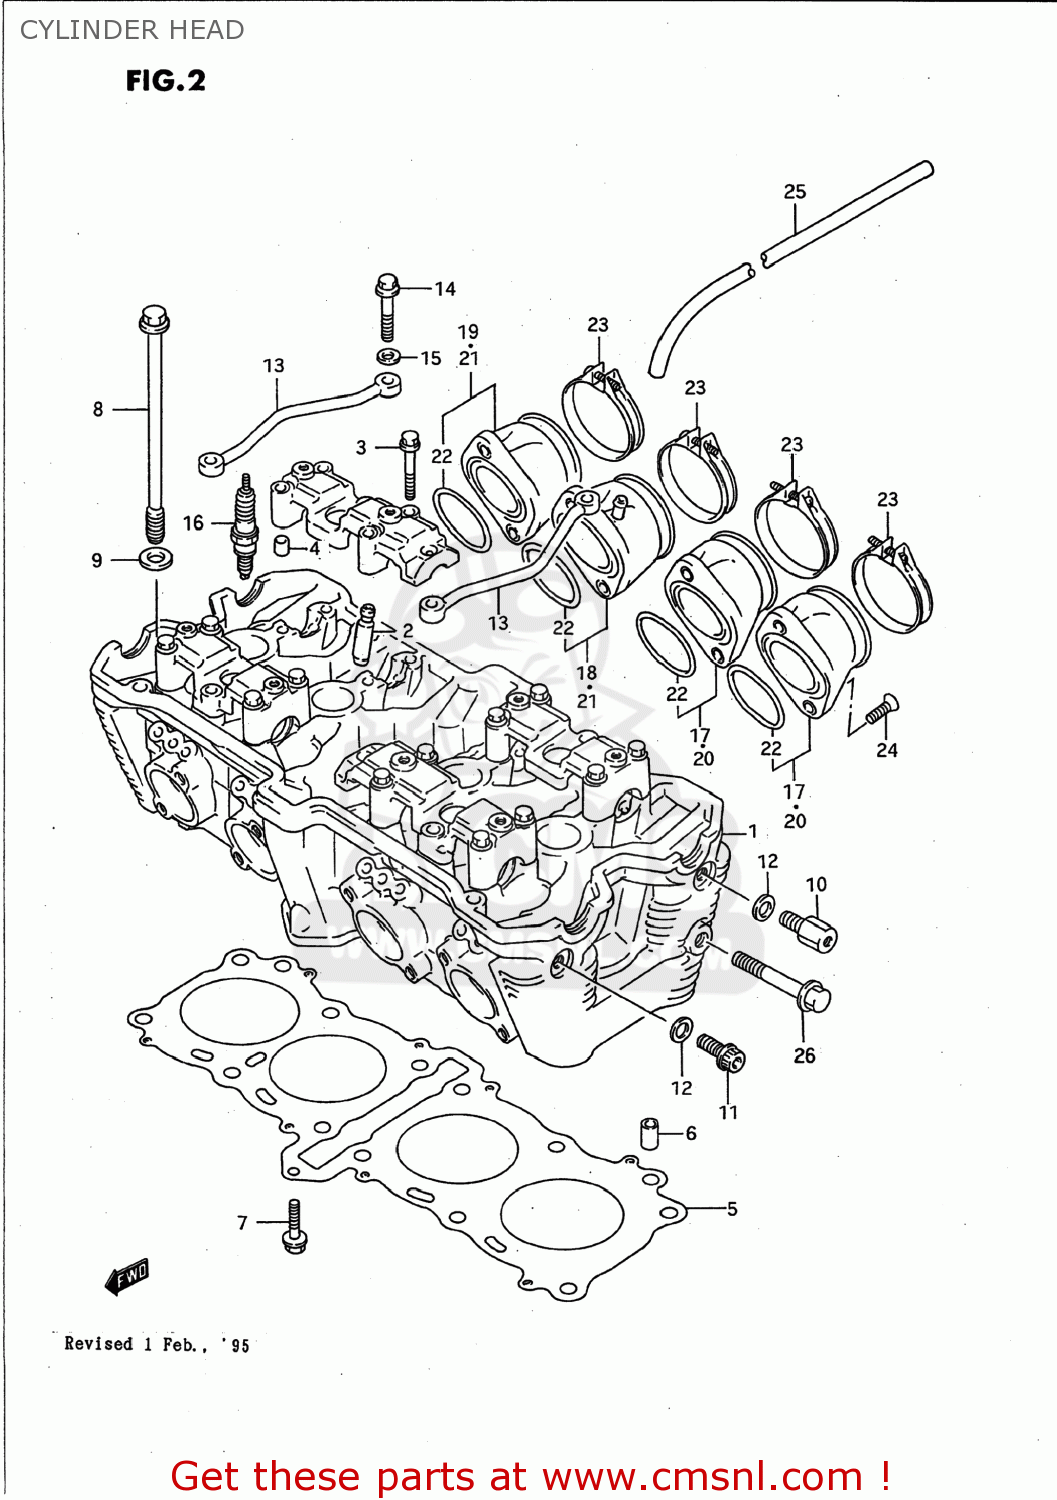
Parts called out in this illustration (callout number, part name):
1	HEAD ASSEMBLY,CYLINDER
2	GUIDE,VALVE
3	BOLT
4	PIN(6.2X8X11)
5	GASKET,CYLINDER HEAD
6	PIN
7	BOLT
8	BOLT(10X160)
9	WASHER(10.5X19X2)
10	BOLT
11	BOLT
12	GASKET(8.2X14X1).6 (NAS)
13	PIPE,CYLINDER HEAD OIL
14	BOLT(6X39)
15	WASHER
16	PLUG,SPARK(CR8E)
17	PIPE ASSEMBLY,INTAKE
18	PIPE ASSEMBLY,INTAKE
19	PIPE ASSEMBLY,INTAKE
20	PIPE ASSEMBLY,INTAKE NO.1
21	PIPE ASSEMBLY,INTAKE NO.2
22	O RING(D:2.4,ID:44)
23	CLAMP
24	SCREW(6X16)
25	HOSE
26	BOLT
